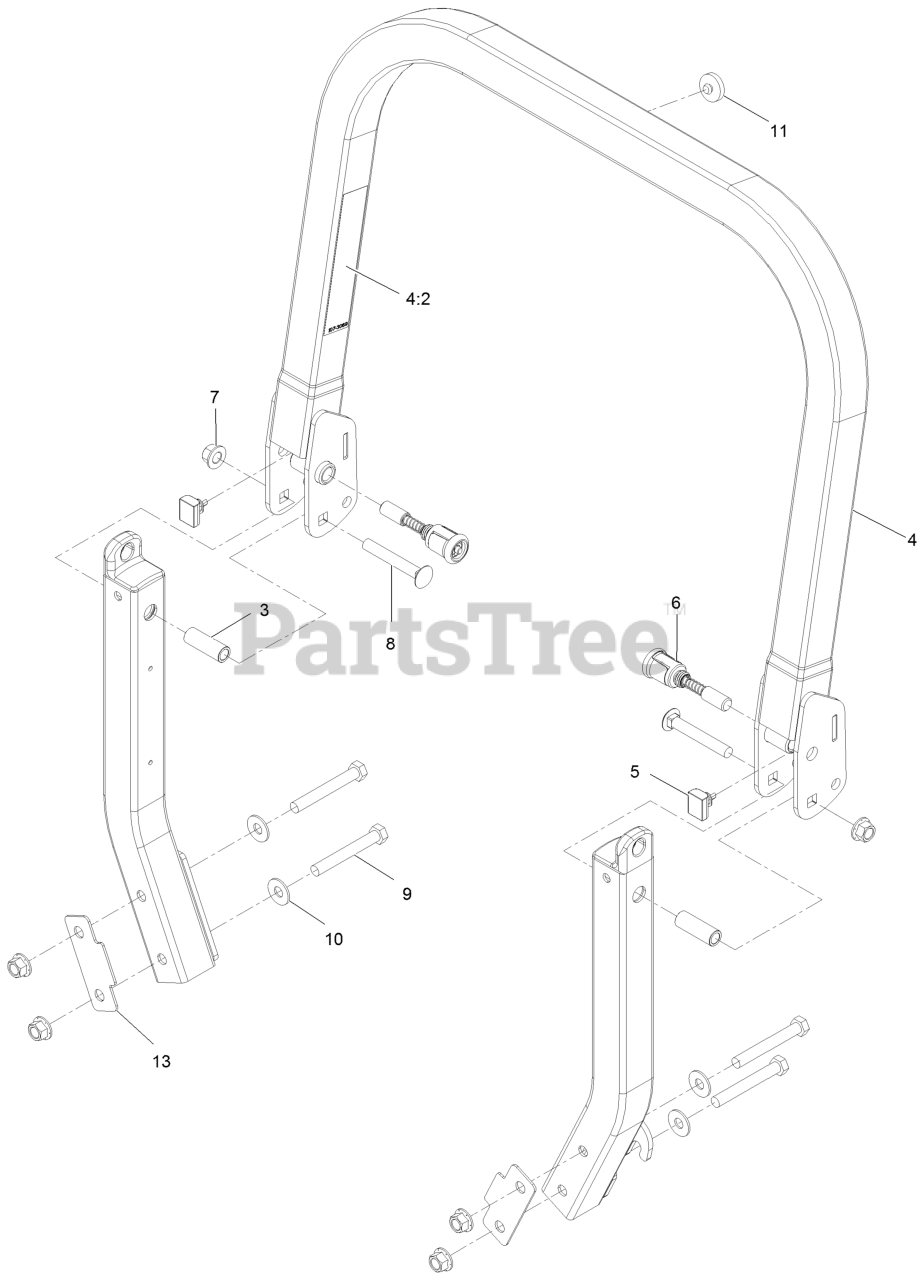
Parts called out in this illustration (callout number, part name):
4	UPPER ROPS ASM
4:2	DECAL-WARNING
5	BUMPER-ROPS
6	PIN-SPRING
7	Nut-Lock 1/2-13
8	SCREW-CARR
9	WASHER-LOCK
10	WASHER-SPRING
11	BUMPER-PUSH-IN, RUBBER
